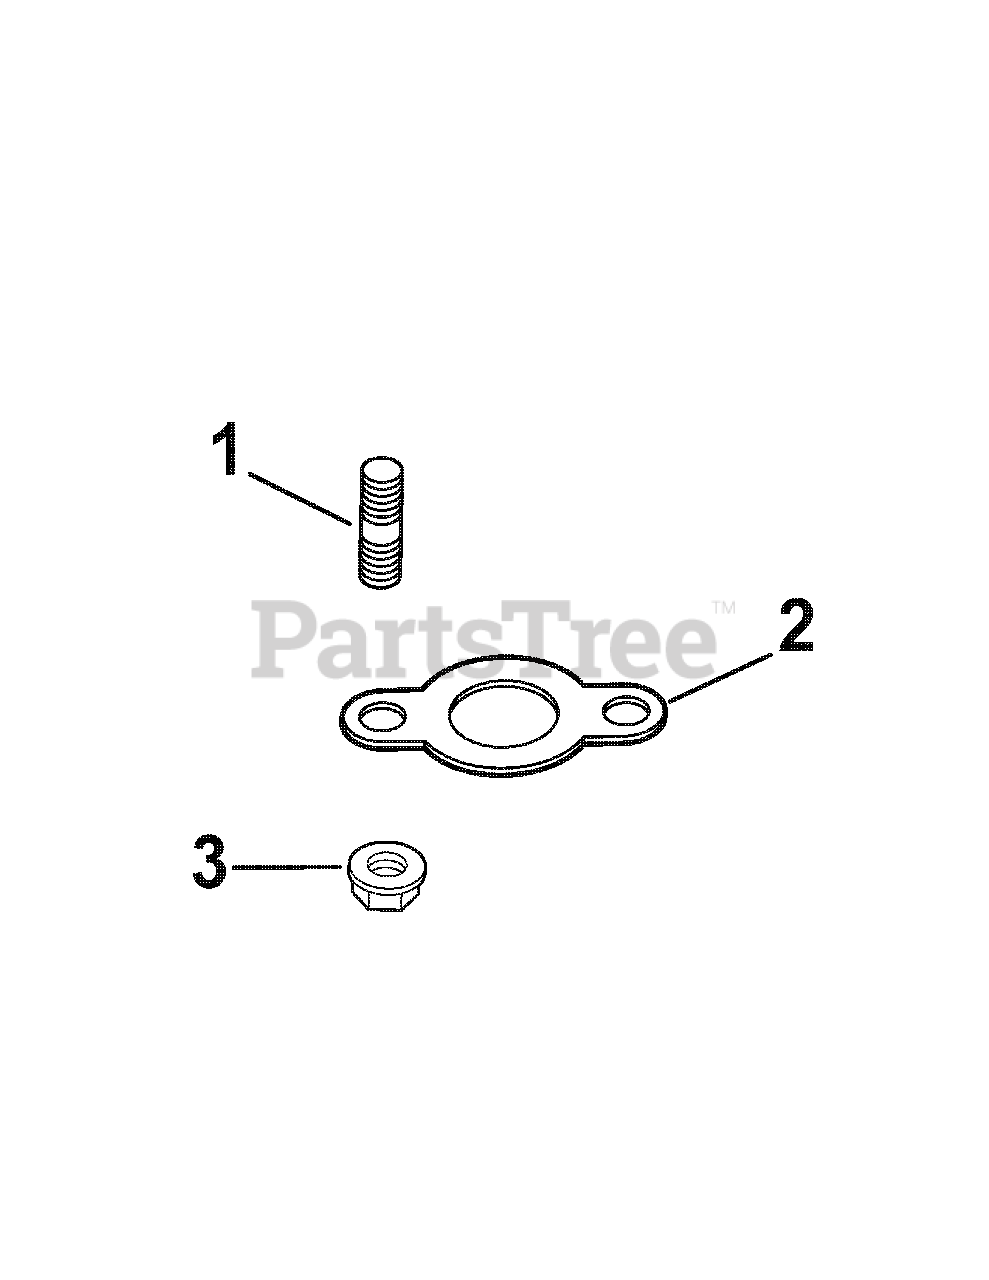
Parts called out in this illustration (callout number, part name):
1	Stud M8x1.25x33
2	Gasket, exhaust manifold
3	Nut, hex. flange M8x1.25
